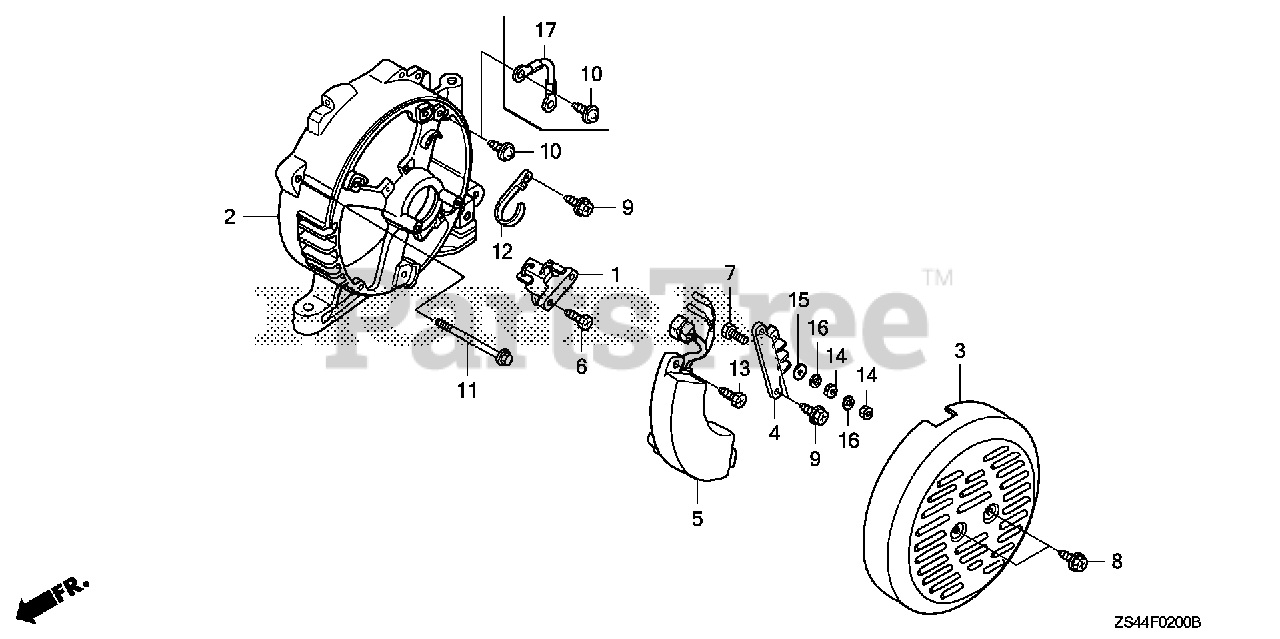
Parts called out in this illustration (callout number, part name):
1	BRUSH ASSY.
2	HOUSING, RR.
3	COVER, GENERATOR END *NH1* (BLACK)
4	TERMINAL, VOLT CHANGE
5	REGULATOR ASSY., AUTOMATIC VOLTAGE
6	SCREW, TAPPING (5X18)
7	BOLT, HEX. (5X20)
8	SCREW, TAPPING (5X12)
9	SCREW, TAPPING (5X14)
10	SCREW, PAN (5X12)
11	BOLT, FLANGE (6X100)
12	TIE, CABLE
13	SCREW, TAPPING (5X16) (NOT AVAILABLE)
14	NUT, HEX. (5MM)
15	WASHER, PLAIN (5MM)
16	WASHER, SPRING (5MM)
